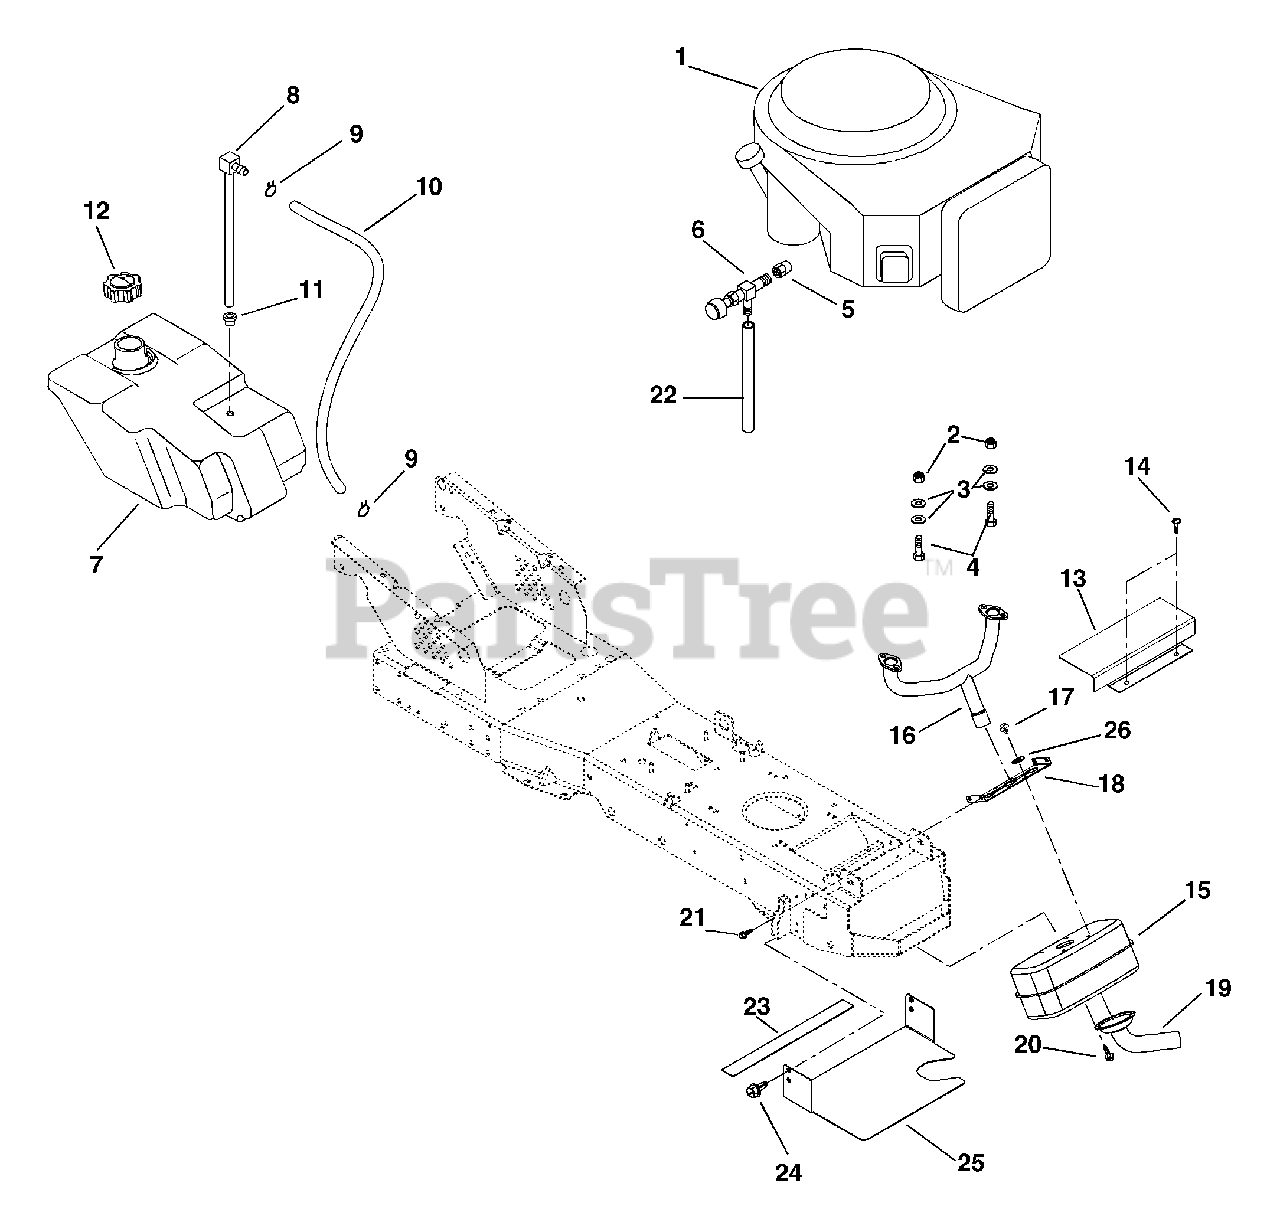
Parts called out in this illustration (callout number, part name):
1	ENGINE, B&S INTEK 22HP V TWIN
2	@NUT-LK-CTR .31-18 YWZC
3	WSHR-FL-STL .328X.875X.062YWZC
4	@BLT-HEX .31-18X1.50 GR5 YWZC
5	ADAPTER, OIL DRAIN
6	COCK, OIL DRAIN
7	FUEL TANK
8	TANK FITTING
9	CLAMP-HOSE WIR.490/.510X.092#8
10	HOSE- FUEL LINE 48.00"
11	BSHG-FLG .375 X 1.062 X .625 R
12	FUEL CAP
13	SHIELD, HEAT
14	@SCR-TAP .31-18X.50 HWH TR YWZ
15	MUFFLER - EXHAUST
16	PIPE, EXHAUST INTEK V TWIN
17	@SCR-TAP 12-24X.75 HWH YWZC
18	BRACKET, MUFFLER
19	DEFLECTOR, EXHAUST
20	SCR-TAP 8-32X.38 SL HWH YWZC
21	SCR-TAP .312-18X.50 HWH TR BL
22	TUBE OIL DRAIN
23	HEAT SHIELD- FABRIC 1X10.75
24	SCR-TAP 12-24X.50 HWH TR BLACK
25	SHEILD, HEAT
26	@WSHR-FL-STL.250X.56X.049 YWZC
